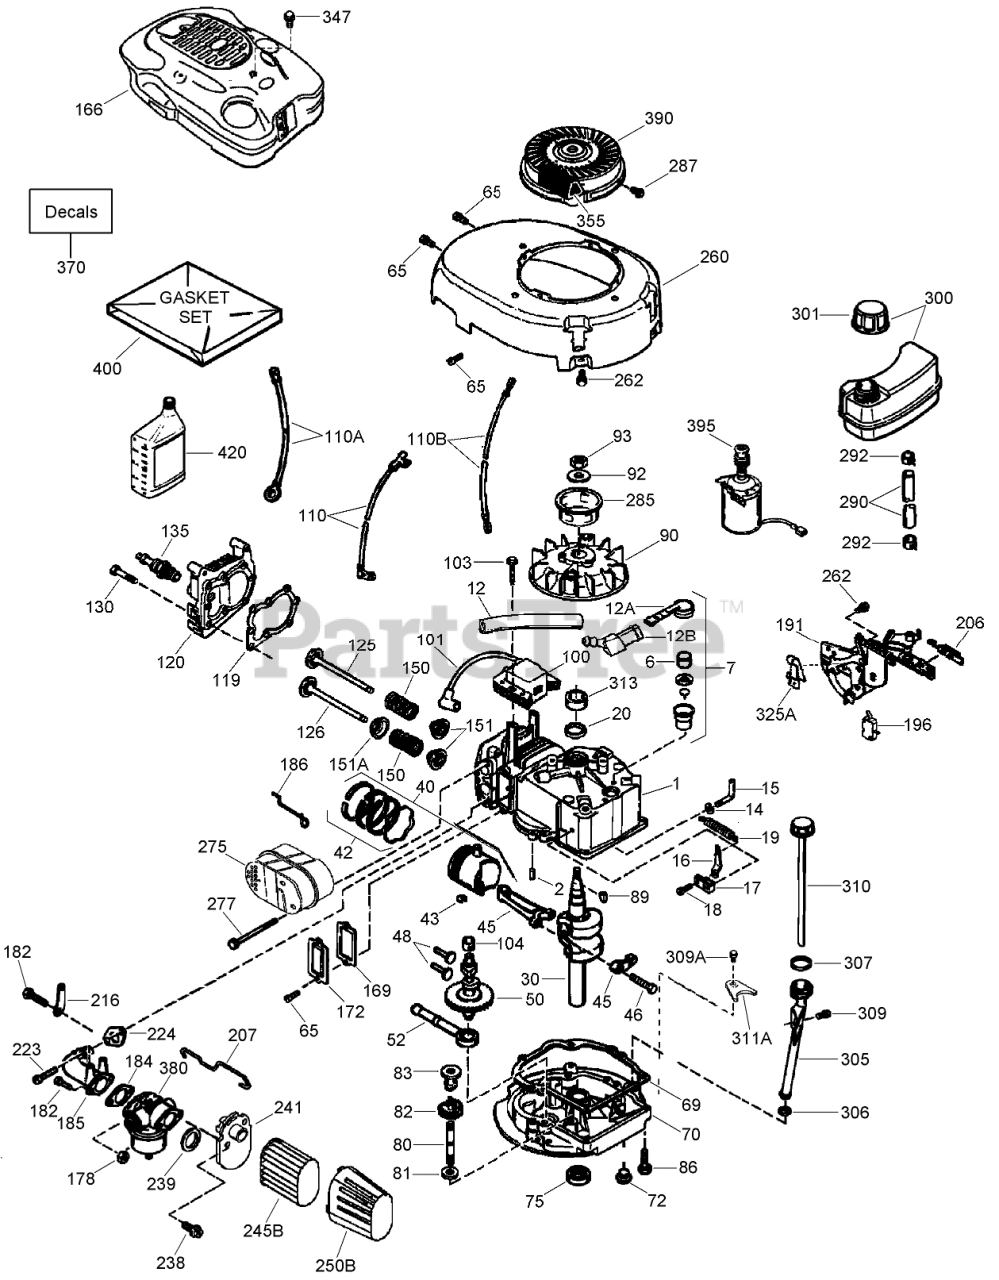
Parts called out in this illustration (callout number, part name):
1	Cylinder Asm (Includes 2, 20)
2	Pin-Dowel
6	Element-Breather
7	Breather Asm (Includes 6, 12A)
12	Tube-Breather
12A	Breather Cover and Tube ASM
12B	Elbow-Tube, Breather
14	Washer-Flat
15	Governor Rod Asm (Includes 14)
16	Lever-Governor
17	Clamp-Lever, Governor
18	Screw (T-15, 8-32 x 19/64)
19	Spring-Extension
20	Seal-Oil
30	Crankshaft
40	Piston, Pin and Ring Set (.010 OS) (Includes 42)
40	Piston, Pin and Ring Set (Std) (Includes 42)
42	Ring Set (.010 O S)
42	Ring Set (STD)
43	Ring-Retaining, Piston Pin
45	Connecting Rod Asm (Includes 46)
46	Bolt-Rod, Connecting
48	Lifter-Valve
50	Camshaft (Exhaust M C R) (Includes 104)
52	Oil Pump ASM
65	Screw (10-24 x 9/16)
69	Gasket-Flange, Mounting
70	Mounting Flange Asm (Includes 72-83, 306, 309A, 311A)
72	Plug-Drain, Oil (Flush Mount)
75	Seal-Oil
80	Shaft-Governor
81	Washer-Flat
82	Governor Gear Asm (Includes 81)
83	Spool-Governor
86	Screw (1/4-20 x 1-1/4)
89	Key-Flywheel
90	Flywheel (Plastic Ring-Gear)
92	Washer-Belleville
93	Nut-Flywheel
100	Ignition-State, Solid
101	Cover-Spark Plug
103	Screw (T-15, 10-24 x 15/16)
104	Bushing-Cam
110	Wire-Ground
110A	Wire ASM
110B	Wire ASM
119	Gasket-Head, Cylinder
120	Head-Cylinder
125	Valve-Exhaust (STD) (Includes 151)
126	Valve-Intake (STD) (Includes 151)
130	Screw (5/16-18x1-1/2)
135	Spark Plug-Resistor (R J19 L M)
